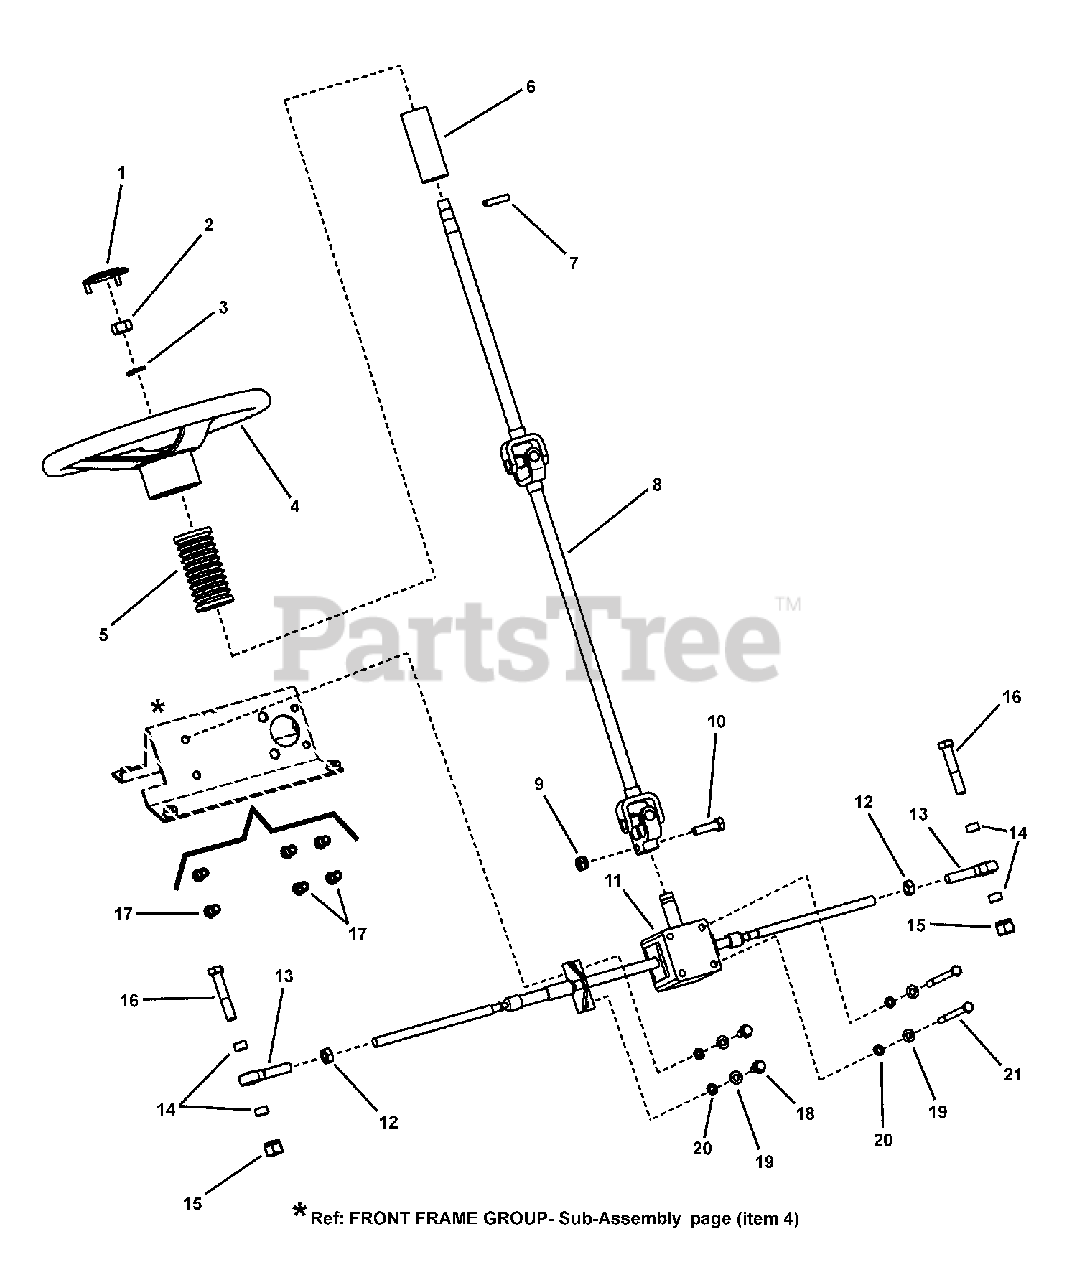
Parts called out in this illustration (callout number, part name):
1	CENTER CAP, Steering Wheel
2	NUT, M16 x 2 thread Hex, GR 5
3	WASHER, 16mm Split Lock
4	* STEERING WHEEL (w/cross drilled hole)
4	STEERING WHEEL, UV-2 (w/40 tooth splined hole)
5	COVER, Steering Shaft
6	COVER, Steering Shaft
7	* ROLL PIN, 5/16 x 1-1/2"
8	* COLUMN, Steering (w/cross drilled hole)
8	COLUMN, Steering (w/40 tooth spline)
9	NUT, 10mm-1.50 Hex Nyloc
10	SCREW, M10-1.50 x 40mm Hex Head Cap
11	ASSEMBLY, Rack and Pinion Steering
12	NUT, 1/2-20 Hex Jam, GR 5 or B
13	BALL JOINT, 1/2-20
14	SPACER, 1/2 I.D., 5/8 O.D. x .375
15	NUT, 1/2-13 Hex Nyloc
16	SCREW, 1/2-13 x 2-3/4 Hex Head Cap, GR 5
17	INSERT, 5/16-18 Hex Threaded
18	BOLT, 5/16-18 x 7/8" Hex Flange Lock
19	WASHER, .34 x .69 x .08 Flat
20	WASHER, .32 x .58 x .08 Split Lock
21	SCREW, 5/16-18 x 3-3/4" Hex Head Cap
